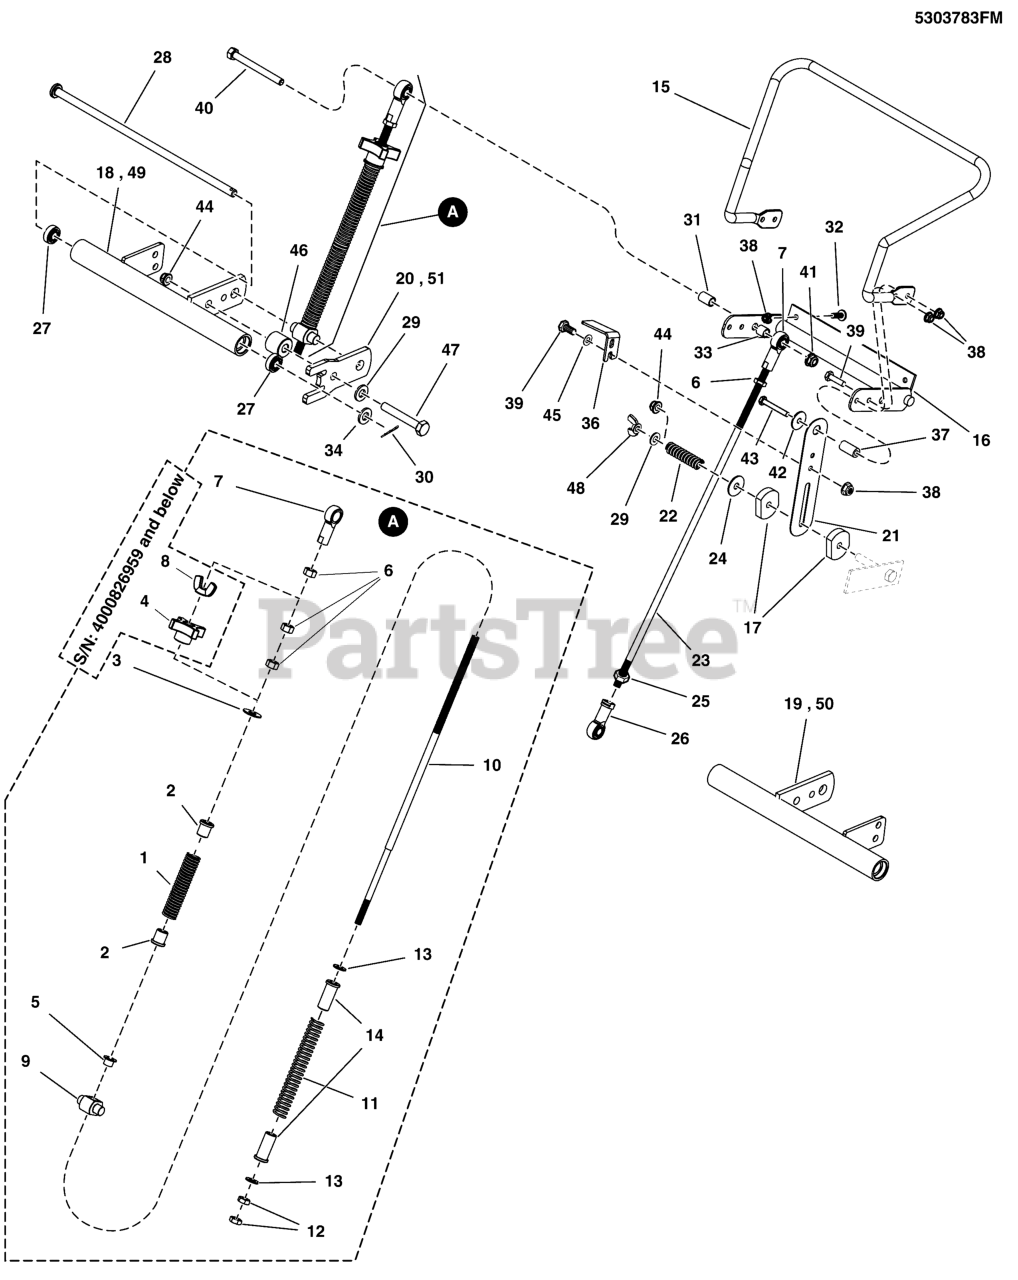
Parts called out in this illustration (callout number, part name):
1	SPRING,COMP,.645IDX8.00LGX.080WR,BLK E-C
2	FLANGED BUSHING, 3/8IDX.63ODX.8125FL
3	WASHER, 3/8 USS
4	KNOB, 4 ARM, 3/8-24
5	BUSHING, .38ID X .47 OD X .38L, FL
6	NUT, 3/8-24 HEX
7	BALL JOINT, 3/8-24 FEMALE
8	WING NUT, 3/8-24, CZ
9	TRUNION, 1/2" POSTS, STAINLESS
10	ROD, 3/8-24 X 16.50,STEP DOWN TO 5/16
11	SPRING, COMP, .60 ID X 5.50 LG, .080W
12	NUT, 5/16-18 HEX
13	WASHER, 5/16" SAE
14	BUSHING, .31IDX.60OD X 1.50L, FL (.75OD)
15	BAR, SPEED CONTROL - BLK
17	PAD, T-712 FRICTION MATERIAL
18	WELD, CENTER PIVOT HUB, RH - WALK - BLK
19	WELD, CENTER PIVOT HUB, LH - WALK - BLK
20	TAB, CONTROL PIVOT - BLK
21	PLATE, FRICTION CONTROL, SS
22	SPRING, COMP, .40 X .60 X 2.25, BLACK
23	ROD, 3/8-24, 19.00, LH-RH CZ
24	WASHER, 5/16 FENDER
25	NUT, 3/8-24 HEX, LH
26	BALL JOINT, 3/8-24 FEMALE, LH
27	BEARING, .375" ID X .875" OD X .341" THK
28	ROD, 3/8 X 12, HEADED - CZ
29	WASHER, 5/16" SAE
30	PIN, COTTER, 1/8 X 1-1/4
31	SPACER, .38 X .50 X .75
32	SCREW-TRUSS HD TORX DR 1/4-20X0.750 T27
33	SPACER, .38 X .50 X .50
34	WASHER, 3/8 SAE
35	BOLT, 3/8-16 X 2, GD5, CZ
36	BRACKET, SWITCH ENGAGEMENT - BLK
37	SPACER, .26 X .50 X 1.00
38	NUT, 1/4-20 HEX NYLOCK FLANGE
39	BOLT-1/4-20 X 3/4 GD5 CZ
40	BOLT, 3/8-16 X 3" GD5 CZ
41	NUT, 3/8-16 HEX NYLOCK FLANGE
42	WASHER, 1/4 FENDER
43	BOLT, 1/4-20 X 2", GD5
44	NUT, 5/16-18 HEX NYLOCK FLANGE
45	WASHER, 1/4 SAE
46	SPACER, .33 X 1.00 X .88, CZ
47	BOLT, 5/16-18 X 2 GD5
48	NUT, Wing, 5/16-18
49	WELD, W35 CONTROL PIVOT, RH - BLK
50	WELD, W35 CONTROL PIVOT, LH - BLK
51	TAB, PIVOT, W35 - BLK
